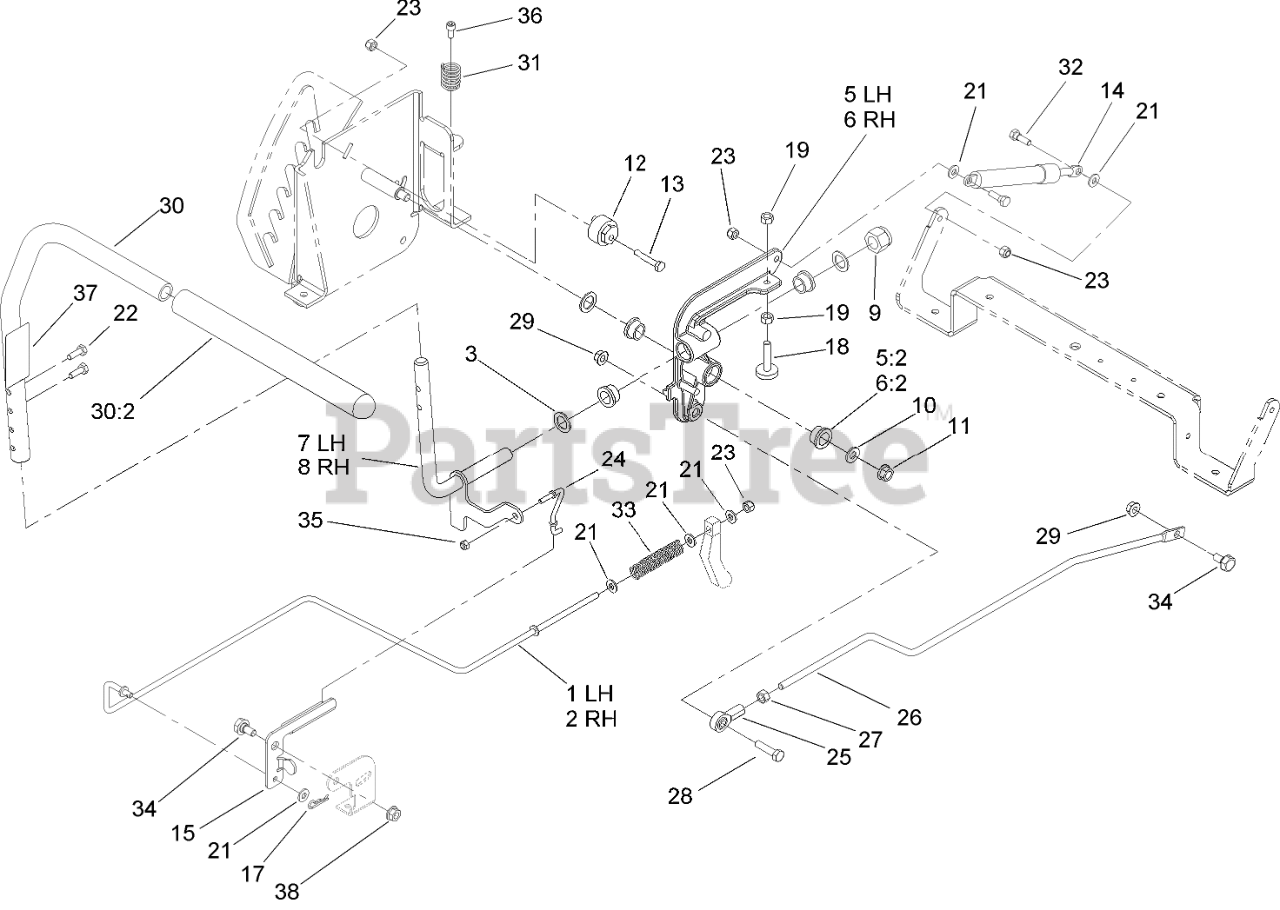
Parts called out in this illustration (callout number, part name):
2	ROD-BRAKE, RH
3	WASHER-THRUST
6	RH ACTIVATOR ARM ASM
6:2	BUSHING
8	RH PIVOT SHAFT ASM
9	NUT-LOCK, NI
10	WASHER-FLAT
11	NUT-LOCK, NI
12	ECCENTRIC
13	SCREW-HH
14	Damper-Control, Motion
15	BELLCRANK
17	PIN-COTTER
18	STOP-ADJUSTMENT
19	NUT-HEX
21	WASHER-FLAT
22	SCREW-HH
23	NUT-LOCK, NI
24	LINK-BRAKE
25	BALLJOINT-RH
26	ROD-HYDRO
27	NUT-HEX
28	SCREW-HH
29	NUT-HF
30	HANDLE ASM
30:2	GRIP-CONTROL, MOTION
31	SPRING-COMPRESSION
32	BOLT-SHOULDER
33	SPRING-COMPRESSION
34	BOLT-SHOULDER
35	NUT-LOCK, NI
36	SCREW-HSH
38	NUT-HF
